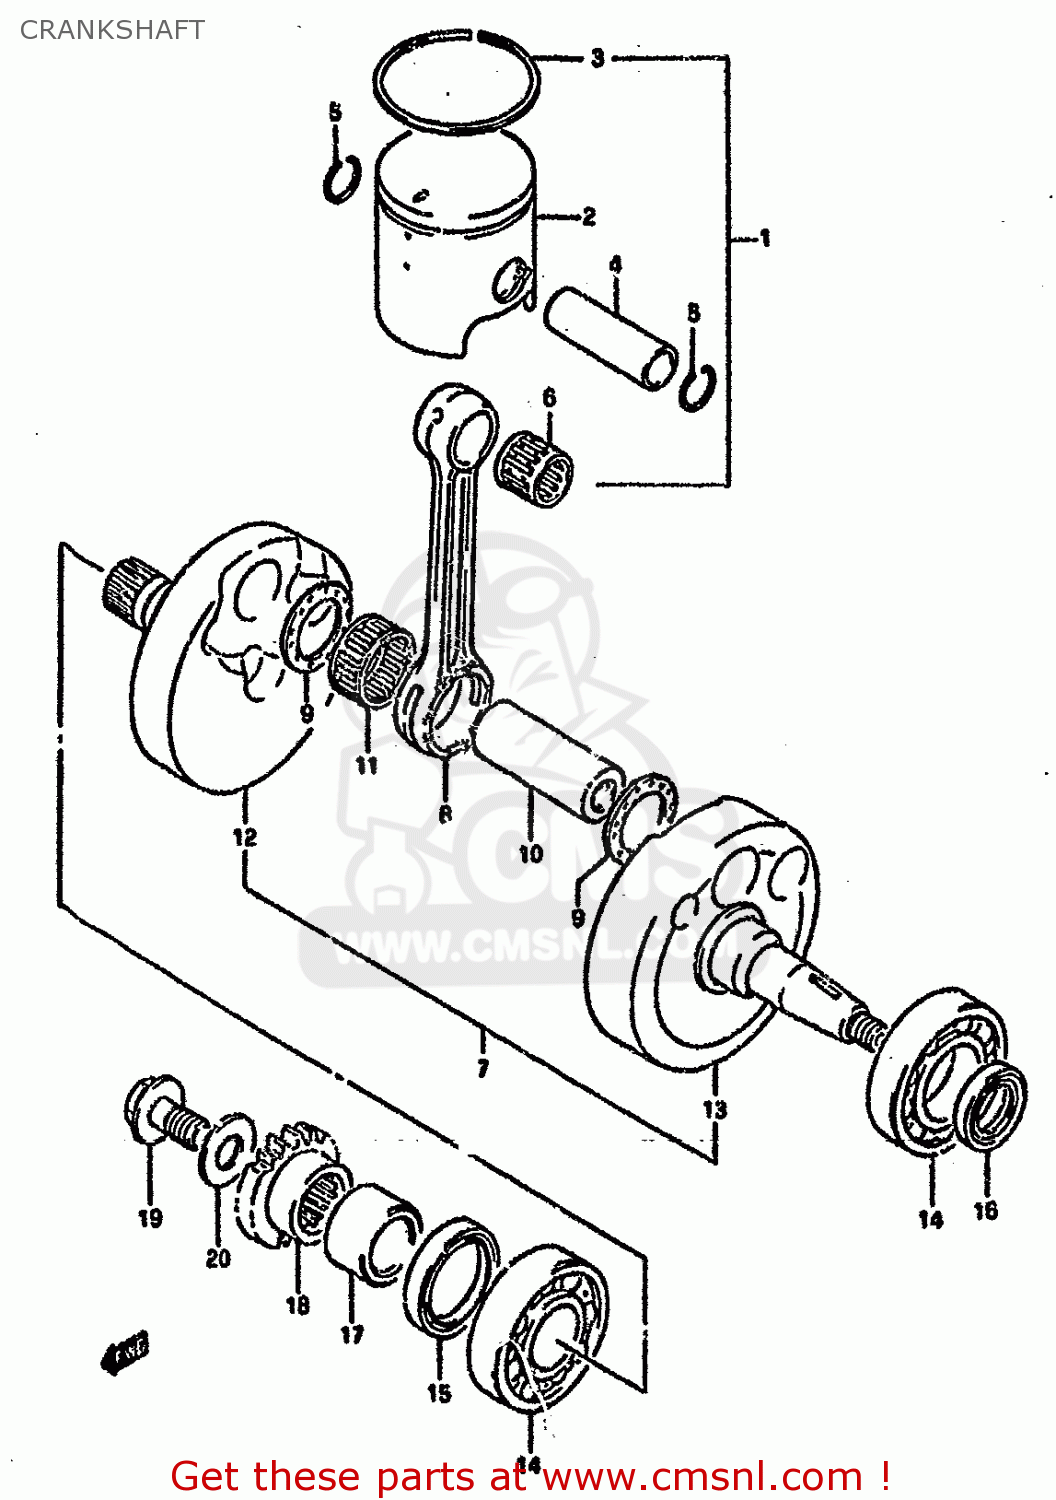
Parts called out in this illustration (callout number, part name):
1	PISTON KIT
2	PISTON
3	RING,PISTON
4	PIN,PISTON
5	CIRCLIP
6	BEARING(15X19X20)
7	CRANKSHAFT ASSY
8	ROD,CONNECTING
9	WASHER(22X36X1.5)
10	PIN,CRANK
11	BEARING(22X28X16)
12	CRANKSHAFT,R
13	CRANKSHAFT,L
14	BEARING(22X56X16)
15	SEAL,OIL(30X40X7)
16	SEAL,OIL(18X30X6)
17	SPACER,PRIMARY DRIVE GEAR
18	GEAR,PRIMARY DRIVE (NT:
19	BOLT,PRIMARY DRIVE GEAR
20	WASHER
